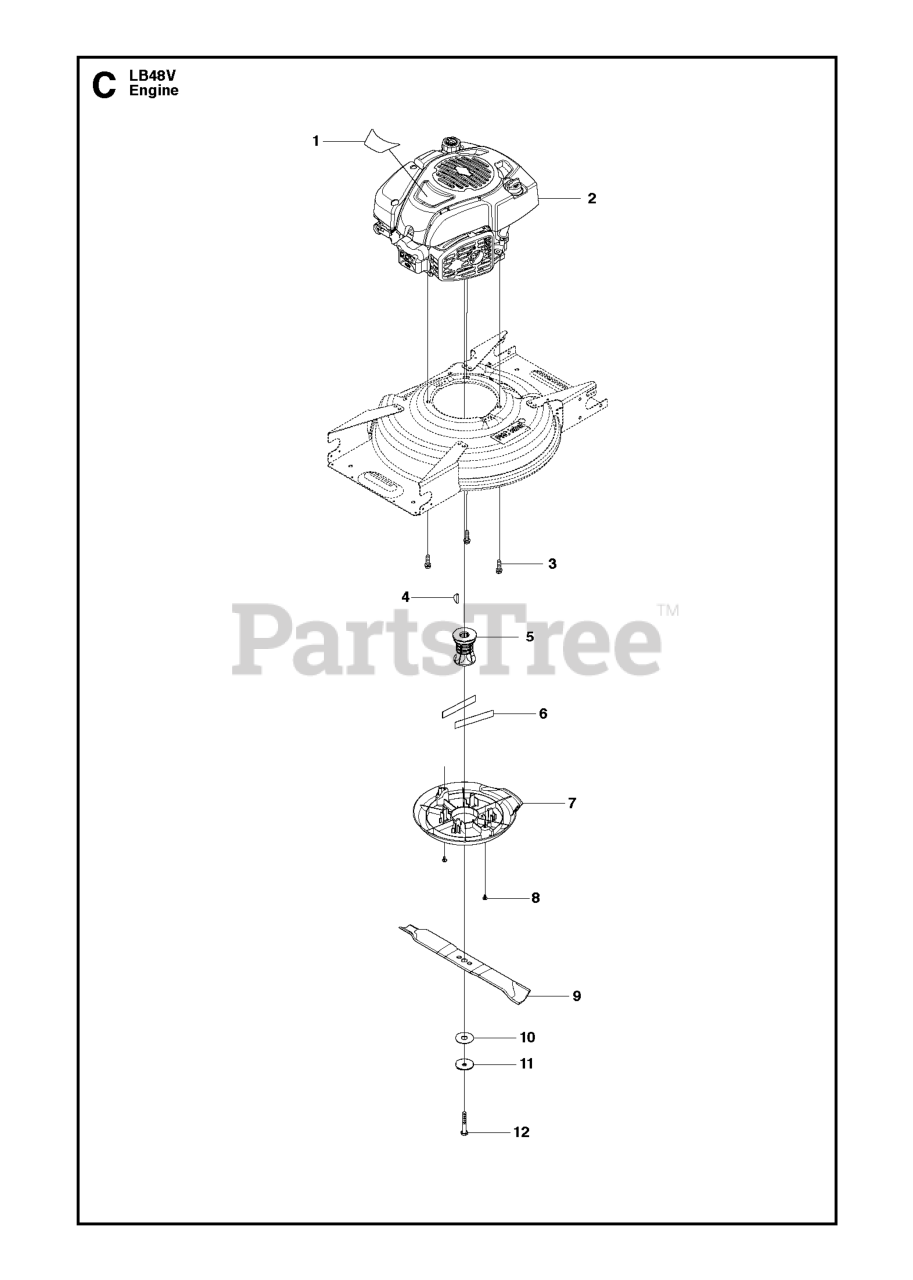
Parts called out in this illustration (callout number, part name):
1	ABSORBER
2	KEY 1/4 X 2.5
7	HUB.ASM.WHEEL.REAR.23"TEX
7	BELT COVER A009-2
15	WASHER
17	SPRING.BRAKE.K46
26	SPRING.RETURN.CRUISE
29	ROD.BRAKE.K66
33	E RING HYT
35	ROD .BRAKE. PARKING. GT. HUSQ.
42	PEDAL COVER T
43	SCREW.MACHINE.CR.1/4-20
50	IDLER.FLAT.910.OFFSET
51	NUT LOCK FLG 3/8-16 UNC
52	IDLER.V-GROOVE.910.OFFSET
64	SHAFT.ASM.PEDAL.BRK.CNTR
70	CONSOLE.ASM.RH.GT.FC.HUSQ
73	BOLT HEX 5/16-18 GR 5
74	SCREW.HI-LO.CONSOLE
80	STRAP.TORQUE.K66
92	BOLT
99	ROD.SPRING.BYPASS.K66.GT.Z
116	NUT LOCK HEX FLANGE 5/16-18
125	SCREW
153	RETAINER M
159	COTTER PIN
160	RETAINER CLIP
161	SPRING, RETURN LT
163	ROD.PEDAL.CONTROL
166	NUT.PUSH.625
167	LATCH.BRAKE.SPRING
170	KEEPER.V-IDLER.CENTER.
183	SPACER.AXLE.HG.TEX
184	RB HANDLE.PARKG.BRK.HUS/PRED
186	SPACER.RETAINER
187	WASHER 12/32X2X10GA
188	RP.LINK.CLUTCH.GROUND.DRIVE
189	BELLCRANK.GROUND.DRIVE.TEX.
190	KEEPER.BELLCRANK.DRIVE
196	SCREW 3/8-16X1
197	BRKT.ANIT-ROTATION.CLUTCH
206	BRACKET.MOUNT.CRUISE.LATCH
207	LATCH.CONTROL.CRUISE
208	GEAR.SECTOR.CONTROL.CR
209	ROD.CONTROL.CRUISE.GT.
210	ROCKER.ASM.PEDAL.CONTR
211	BEARING.NYLON
213	KNOB.CONTROL.CRUSIE.HU
214	PEDAL.FORWARD.HUSQVARNA.DEALER
215	PEDAL RUBBER REVERSE
220	REFLECTOR.RH.TEX GT
221	RETAINER.SPRING.CLIP.H
222	WASHER 21/32 X 1-1/4 X 10 GA.
225	KEEPER.BELT.TRANSAXLE.K66
226	BRACKET.MOUNT.TORQUE.K66.TG
282	BOLT HEX FLGHD 5/16-18X3 GR. 5
284	NUT.U-CHNL.1/4-20.550DP.350PNL
366	BRACKET.REINFORCEMENT
